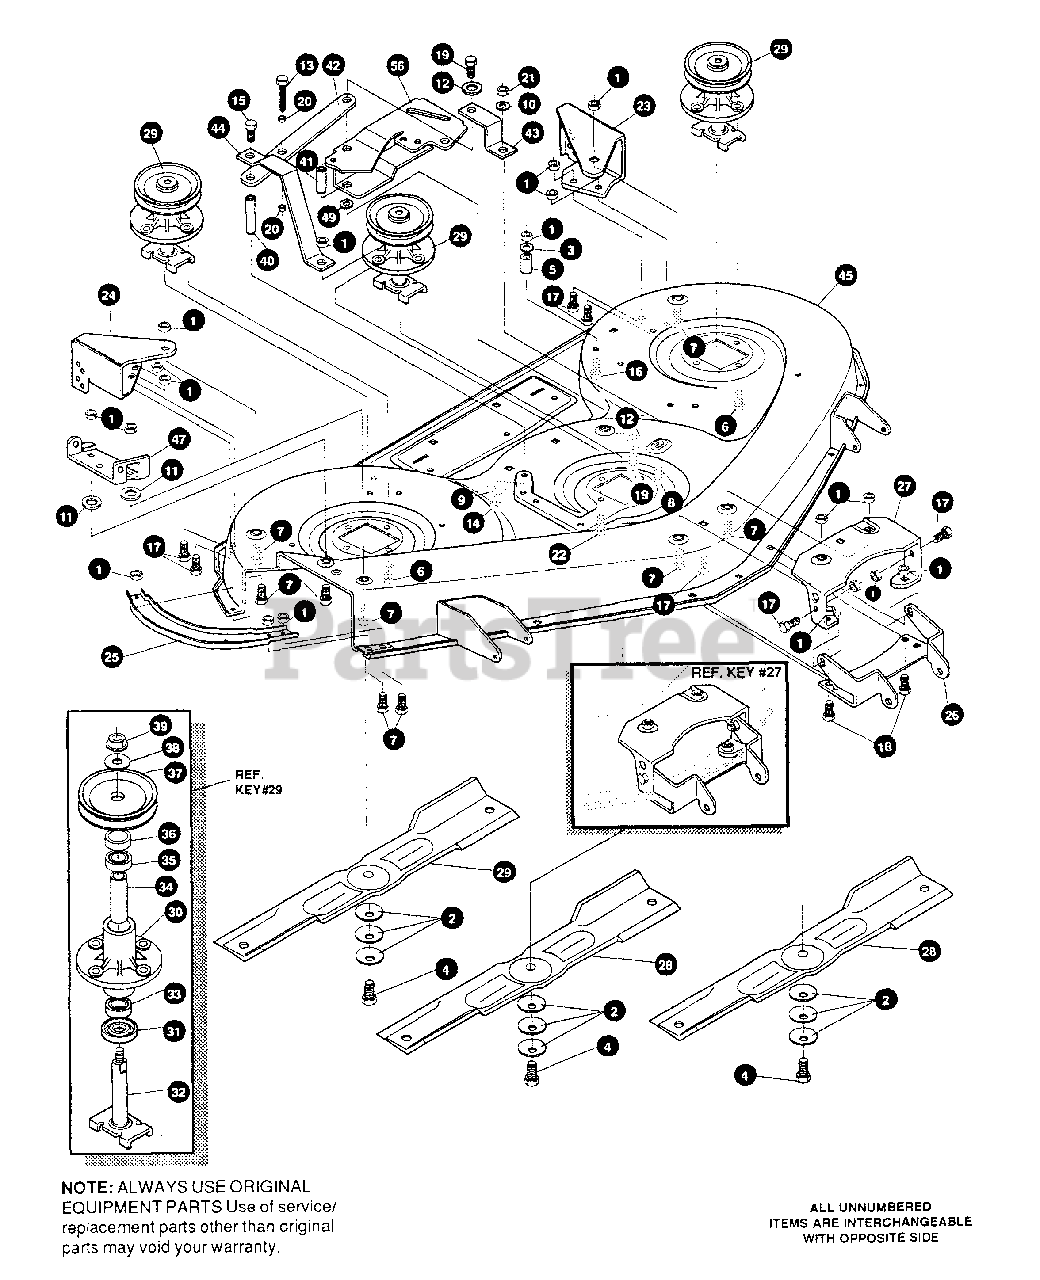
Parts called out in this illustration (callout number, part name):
1	NUT, 5/16-18 REGHEXCTRLK
2	WASHER,.39 IDX 1.25DX .07
3	WASHER, FLAT.328X 1.06X .062
4	SCREW, 3/8-24X 1.00 NYLHH
6	SCREW, 5/16-18X .88 WAHHTAP
7	BOLT, 5/16-18X .63 CARR
8	BOLT, 3/8-16X .75 CARR
9	WASHER, REGSPTLK .393X .68 X .10
10	WASHER, FLAT .406X .81 X .065
11	WASHER, FLAT .469X .92 X .065
12	WASHER, HVSPTLK .328 X .60X .09
13	SCREW, 1/4-20X 1.75 HHC
14	SCREW, 3/8-16X .75 HHC
15	SCREW, 3/8-16X 2.50 HHC
16	BOLT, 5/16-18X 1.00 CARR
17	SCREW, 5/16-18X .63 HHC
18	SCREW, 5/16-18X 1.00 HHC
19	SCREW, 5/16-24X .88 HHC
20	NUT, 1/4-20 REGHEXCTRLK
21	NUT, 3/8-16 HEXKEPS
22	SCREW, 5/16-18X 1.38 WATAP
23	MS BRKT GAUGE WHEEL LH
24	MS BRKT GAUGE WHEEL RH
25	MS BRACE, SKID
26	MS BRKT, MOUNTING 46" DECK
27	MS LIFT SUPT. BRKT
28	BLADE, 16.13 HIGH-LIFT
29	SF QUILL 46" DECK W/ZERKS
30	QUILL CASTING 46" DECK
31	MS DUST SHIELD
32	WS SHAFT/SADDLE 46" DECK
33	BRNG, BALL .669 IDX 1.574 OD X .47
34	SPACER, SLEV .669X .88X 4.281
35	BRNG, BALL .669 IDX 1.574 OD X .47
36	SPACER QUILL, 46" DECK
37	46" QUILL PULLEY SPLIT-STEEL
38	WASHER, SPECIAL QUILL 46"
39	NUT, 7/16-20 WDFLLK
40	SUPPORT SHAFT
41	IDLER SHAFT 46" DECK
42	SUPPORT, STRAP
43	BRACKET, IDLER SUPPORT
44	BRACKET, PULLEY SUPPORT
45	WS MOWER DECK 46" SD
46	MS/MP IDLER ARM 40/43/46
47	MS BRKT CHUTE MOUNT 46"
48	WASHER, FLAT .531 X 1.06X .063
